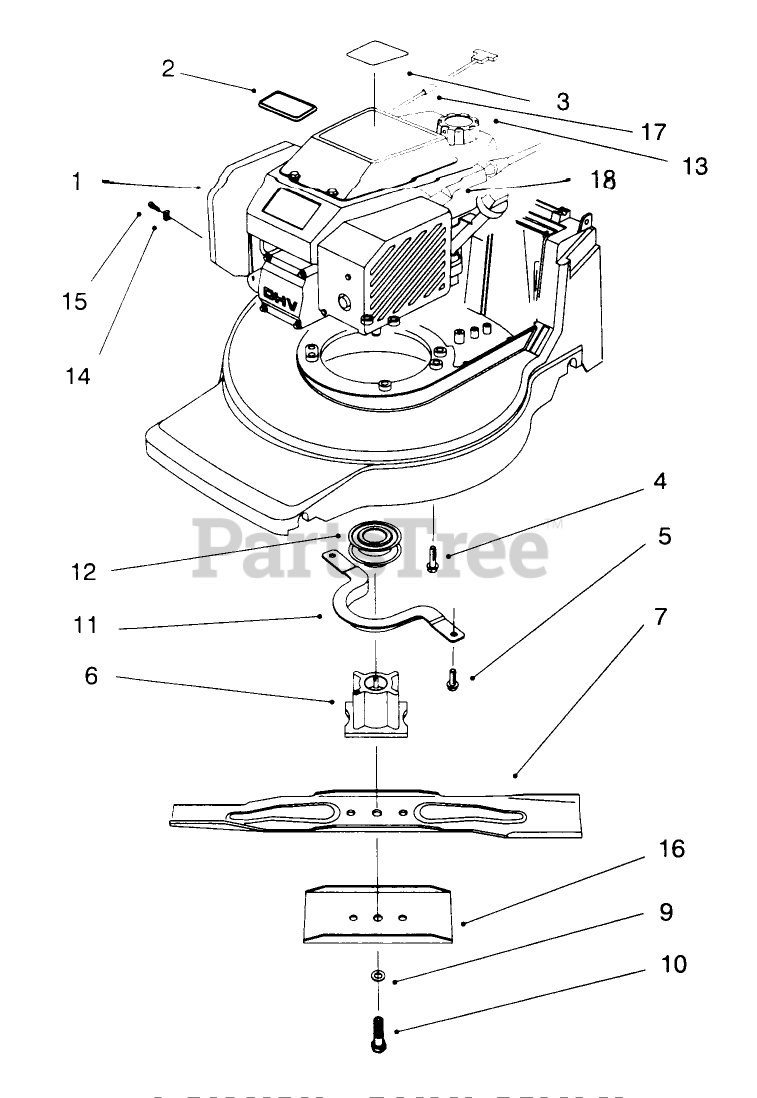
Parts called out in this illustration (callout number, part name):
1	Engine
2	PLATE-LOGO
3	DECAL - ENGINE
4	SCREW-HWH
5	SCREW-HWH
6	BLADE RETAINER - 25 MM
7	Blade
9	WASHER-LOCK
10	BOLT-BLADE
11	Guide-Belt
12	PULLEY-DRIVE, ZONE START
13	CAP-GAS
14	CLAMP-CASING
15	CLAMP SCREW F/W ENGINE
16	Stiffener Blade
17	STOP-ROPE
18	COVER - BRAKE F/W
